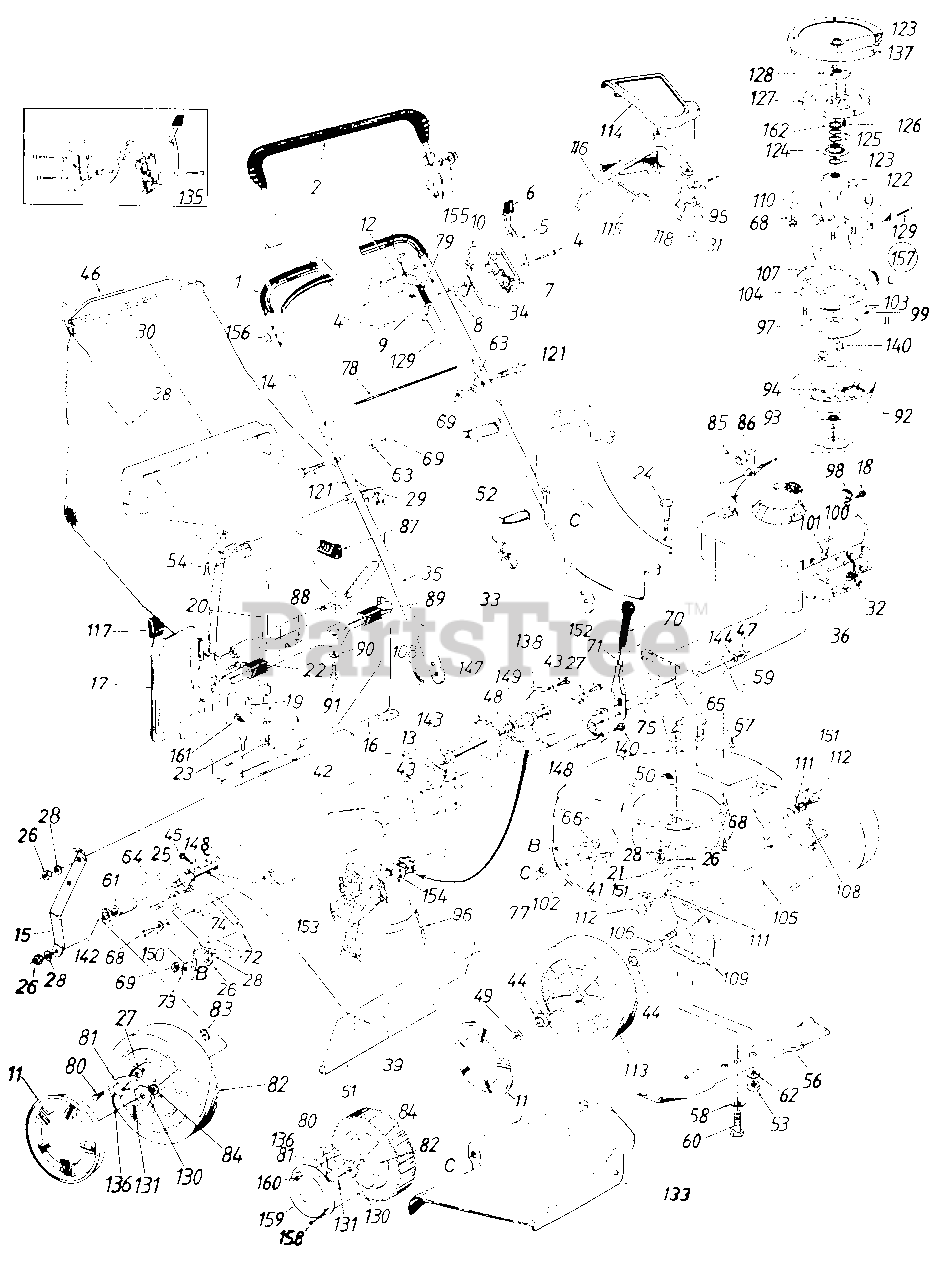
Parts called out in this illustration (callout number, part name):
1	Foam Grip
2	Control Handle Ass'y.-L.H.
3	Top Discharge Chute Ass'y
4	Truss Mach. Scr. #12 x 1.50" Lg.
5	Lockout Spring
6	Spring Lever Knob
7	Control Panel Half
8	Control Disc Pin
9	Clutch Panel Half
10	Throttle Control Lever
11	** Hub Cap
12	Lock Pin .314" Dia. x 1.75"
13	Cotter Pin 3132" Dia. x .75"
14	Upper Handle-Chrome
15	Panel Support Brkt.
16	Top Catcher Panel Ass'y.
17	Top Discharge Door
18	Hex B-Tap Scr. #10 x .38"
19	Torsion Spring
21	Carriage Bolt 1/4-20 x .62"
22	Truss Mach. Scr. 1/4-20 x .5" Lg.
23	Hex Bolt 1/4-20 x .50" Lg.
24	Shoulder Bolt .312 Dia. x .18 Lg. Special
25	Hex Bolt 1/4-20 x .62" L9.
26	Hex Nut 1/4-20 Thd.
27	Bell-Wash. 1/4" I.D.
28	L-Wash. 1/4" I.D.
29	Front Grass Catcher Frame
30	Grass Catcher Handle
31	S.P. Control Cover
32	Spark Plug Insulator
33	Wing Nut
34	Throttle Control Wire 58" Lg.
35	Lower Handle-Chrome
36	Engine
38	21" Top Discharge Grass Bag-Black
39	Retaining Strip
41	Fl-Wash. .344" I.D. x .62"
42	Chain-Axle Ass'y.
43	Hex B-Tap Scr. 1/4" x .38" Lg.
44	** Flange Ball Bearing 1/2" I.D.
45	Hex AB-Tap Scr. 1/4 x .62"
46	Upper Bag Handle
47	Hex Patch L-Nut 3/8-24 Thd.
48	#48 Chain .500" Pitch x 30 Links
49	Hex L-Nut Z r
51	Rear Flap 3.75" x 17.30" Lg.
52	Cable Tie
53	Hex Nut 3/8-24 Thd. (Gr. 8)
54	Hex AB-Tap Scr. #12 x 1.0" Lg.
56	21" Blade
58	Bell-Wash. .46" I.D. x .88" O.D.
59	Height Adj. Rod 19.42" Lg.
60	Hex Bolt 7/16-20 x 2.0" Lg. (Grade 5)
61	Spacer .513" I.D. x .703" O.D. x .69" Lg.
62	L-Wash. 3/8" I.D.
63	L-Wash. 5/16" I.D.
64	R.H. Handle Wheel Brkt. Ass'y.
65	L.H. Handle Wheel Brkt. Ass'y.
66	Carriage Bolt 5/16-18 x .62"
67	Hex Wash. Hd. B-Tap Scr. 5/16-18 x .5" Lg.
68	Hex Wash. Hd. TT-Tap Scr. 3/8-16 x 1.5" Lg.
69	Hex Nut 5/16-18 Thd.
71	Height Adj. Lever
72	Extension Spring .50" O.D. x 3 80n Lg.
73	Bell-Wash. 5116" I.D.
74	Spacer .385" I.D. x .502" O.D. x .270" Lg.
75	Shld. Spacer .500" Dia. x .1 00
77	Bolt Retainer 1/4 x .50" O.D.
78	Instruction Label
79	Control Label
80	Shld. Scr. .342" Dia. x .268
81	Pawl
82	Wheel Ass'y. Comp.
83	Flat Weld Nut 1/4-20 Thd.
84	** Sleeve Bearing 1/2" I.D.
85	Pop Rivet .156" Dia. x .379"
86	Cable Bracket
87	Grass Catcher Locking Knob
88	Foam Strip 1" Lg.
90	Spring Wash. .32" I.D.
91	Hex Tap Scr. 1/4-20 x .75" Lg.
92	Clutch Blade Housing Ass'y.
93	Ball Brg. .669" I.D. x 1.574n
94	Comp. Spring .35" O.D. x 2.0" Lg.
95	S.P. Cable x 50" Lg.
96	"V"-Belt
97	Clutch Cone
98	Casing Clamp
100	Hex B-Tap Scr. #10 x .62"
101	Casing Clamp
104	Brake Cup Cone
105	Front Axle Ass'y.
106	Sleeve .526" I.D. x .690n O.D. x .880" Lg.
107	Ext. Spring 1.75" Lg.
108	Intern. Cotter Pin 5/16" Dia.
109	Extension Spring .50" O.D. x 3.20" Lg.
110	Clutch Housing
111	Intern. L-Wash. 3/8 I.D.
112	Shld. Bolt .623" Dia. x .425
113	Wheel Ass'y. Comp.
114	Self-Propelled Control Cover
115	Self-Propelled Control Cover
116	Control Lever
117	Door Grip
118	Fl-"C"-Sunk Hd. Tap Scr. #10 x .75" Lg.
121	Curved Carr. Bolt 5/16-18 x 1.38" Lg.
122	Fixed Pulley Adapter
123	Serrated Washer 1.0" I.D.
124	Serrated Pulley Half
125	Wave Washer 1.005" I.D.
126	Flat HD Tap Scr. 1/4-20 x .625" Lg.
128	Flywheel Adapter
129	Control Cable-49" Lg.
130	Ratchet Wheel 1.62" O.D.
131	Cotter Pin 1/8" Dia. x 1.00" Lg.
133	Side Chute Deflector Ass'y.
135	Kit-Control Housing Comp.
136	Spring-Nylon
137	Engine Mounting Plate Cover
138	Chain Cover
140	Hex Wash. S-Tap Scr. 1/4-20 x.50" Lg.
142	Fl-Wash. .510" I.D. x 1.0" O.D.
143	Hex Flange Brg. .506" l.D.
144	Fl-Wash. .385" I.D. x .87" O.D.
147	Rear Shaft Ass'y. 21.94" Lg.
148	Hex Flange Bearing .506" I.D. Plastic
149	Fl-Wash. .531" I.D. x .930" O.D.
150	Fl-Wash. .531" I.D. x 1.25" O.D.
151	Flanged Nyliner Brg.
152	Hex Bolt 1/4-20 x .62" Lg. (Grade 5)
153	Transmission Comp.
154	Hex Bearing Cup
157	Blade Brake Clutch Ass'y. Comp.
158	Pan Hd. Tap Scr. #12 x .50" Lg.
160	Hex Ins. L-Nut 1/4-20 Thd.
161	Hex B-Tap Scr. #10 x .38"
162	Serrated Washer
